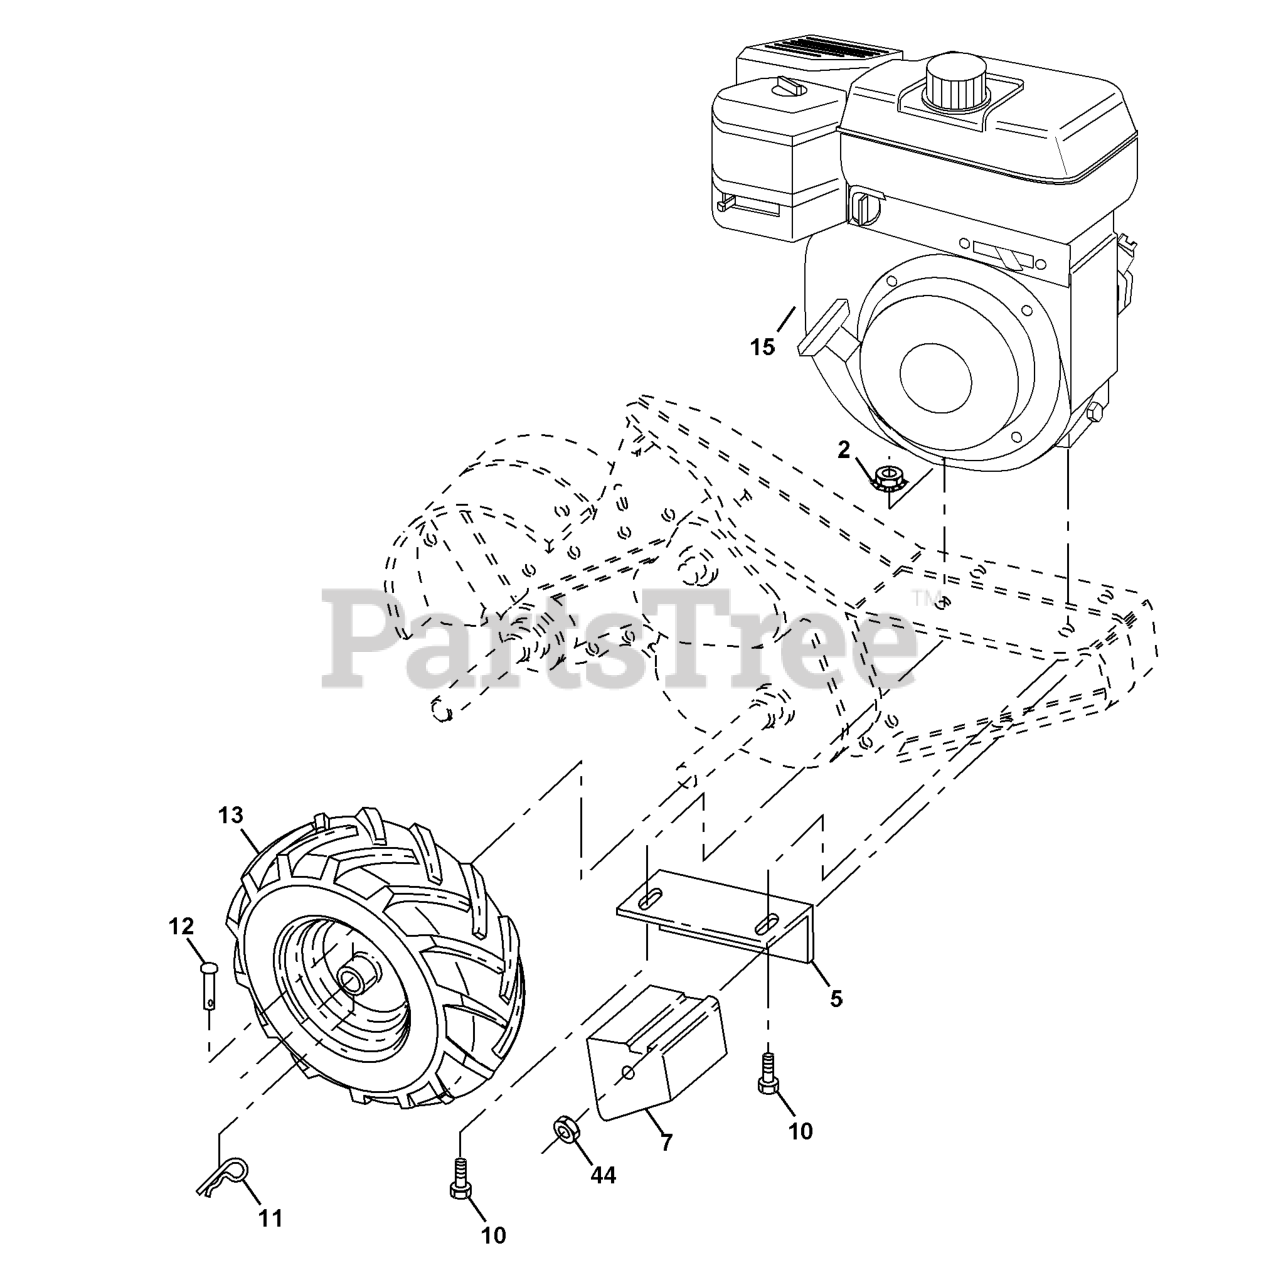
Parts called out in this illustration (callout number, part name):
2	LOCKNUT-FLANGE 5/16-18
5	DNO BRACKET RH CRT
7	COUNTERWEIGHT, RH
10	BOLT
11	RETAINER M
12	RIVET,DRILLED
13	TIRE.16X4-8.CHEVRON.TILLER
15	Engine, Briggs & Stratton
